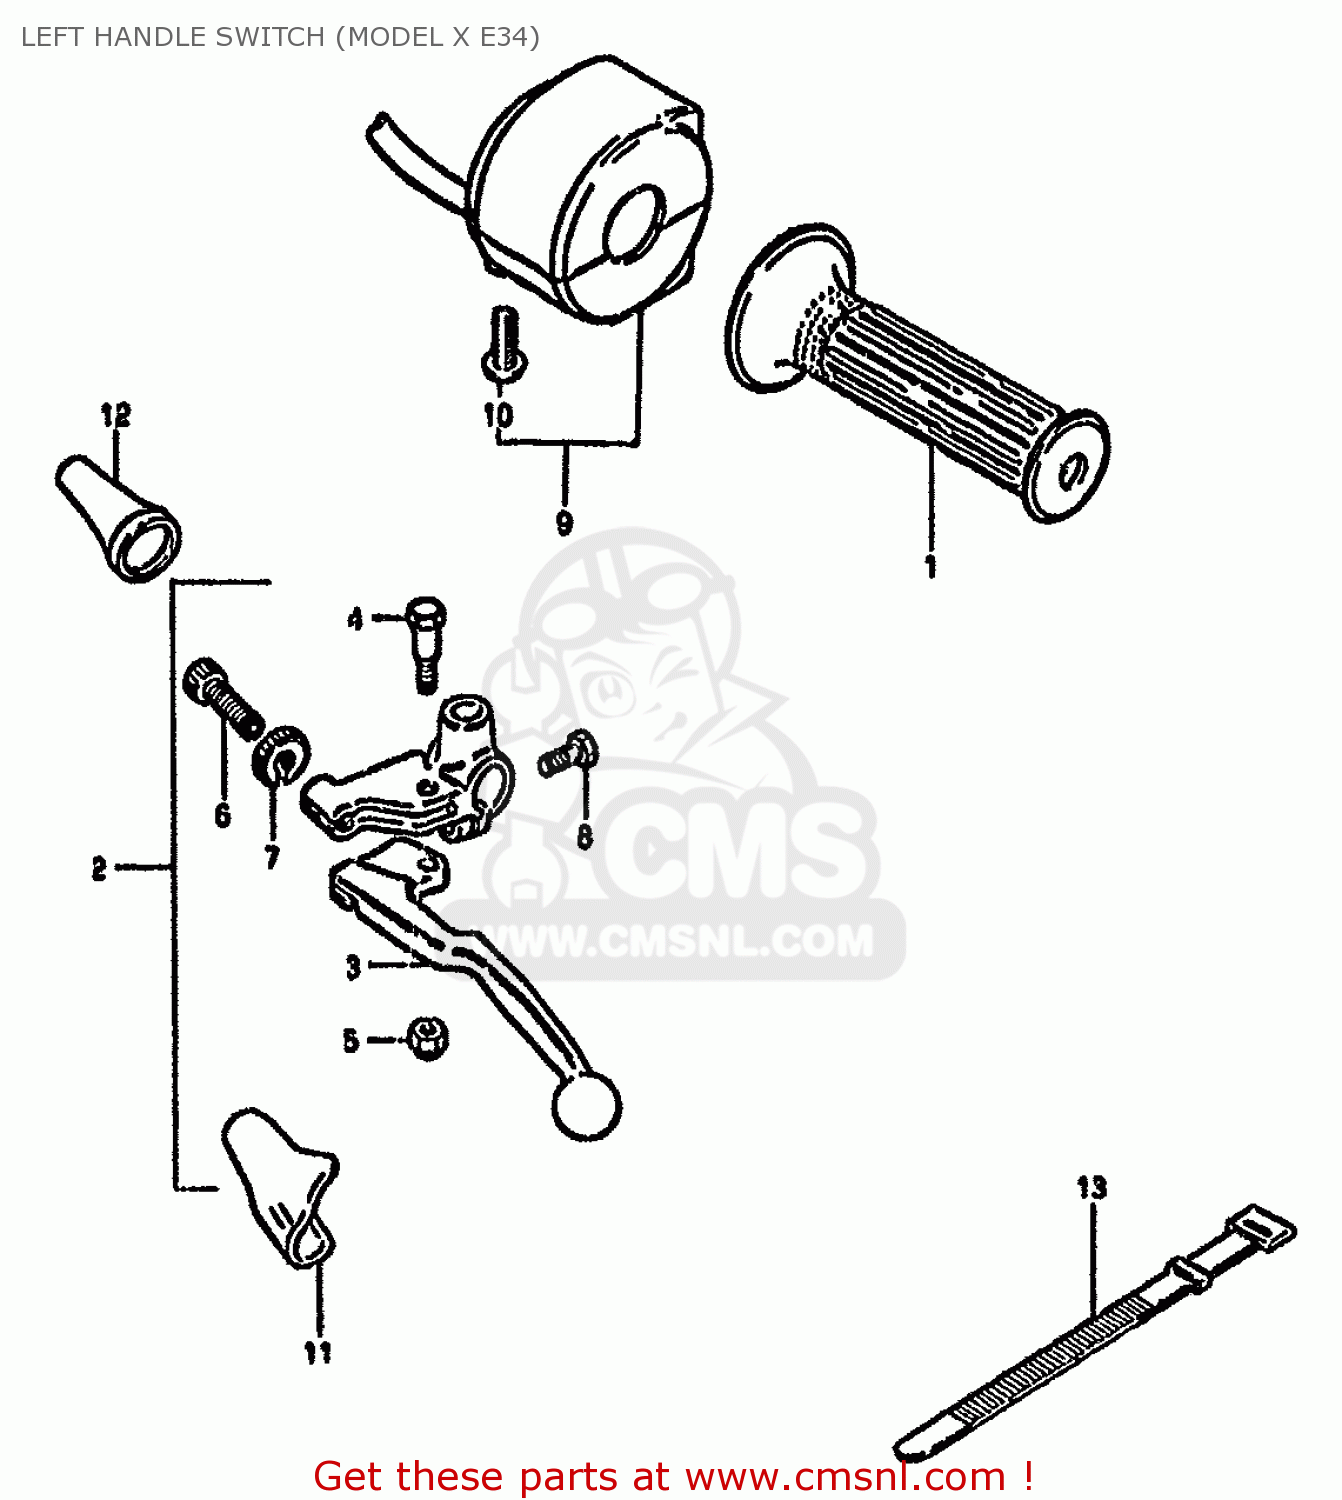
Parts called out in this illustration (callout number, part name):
1	GRIP,L
2	LEVER ASSEMBLY
3	LEVER,CLUTCH
4	BOLT,LEVER
5	NUT 6MM
6	ADJUSTER,CABLE
7	NUT,CABLE ADJUSTER
8	BOLT,CLUTCH LEVER HOLDER
9	SWITCH ASSY, HANDLE LH
10	SCREW
11	COVER,CLUTCH LEVER
12	BOOT,CLUTCH CABLE
13	CLAMP(L:120)
